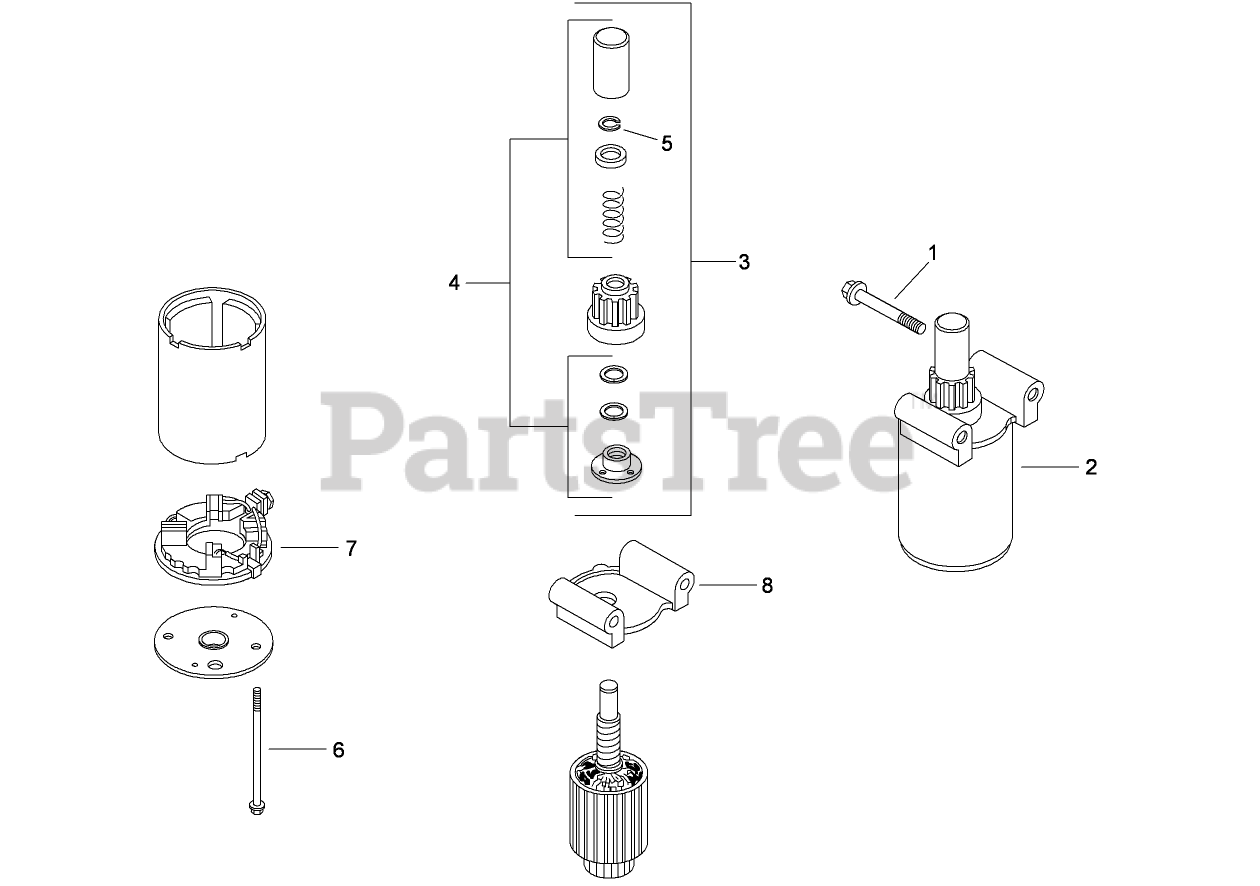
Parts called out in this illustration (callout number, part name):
1	SCREW-FLG (M8X1.25X80)
2	Starter ASM (INCLUDES 3-7)
3	Drive Kit (INCLUDES 4, 5)
4	Drive Parts Kit (INCLUDES 5)
5	RING-RETAINING
6	BOLT-THRU
7	COMMUTATOR-CAP, END
8	CAP-END, DRIVE
